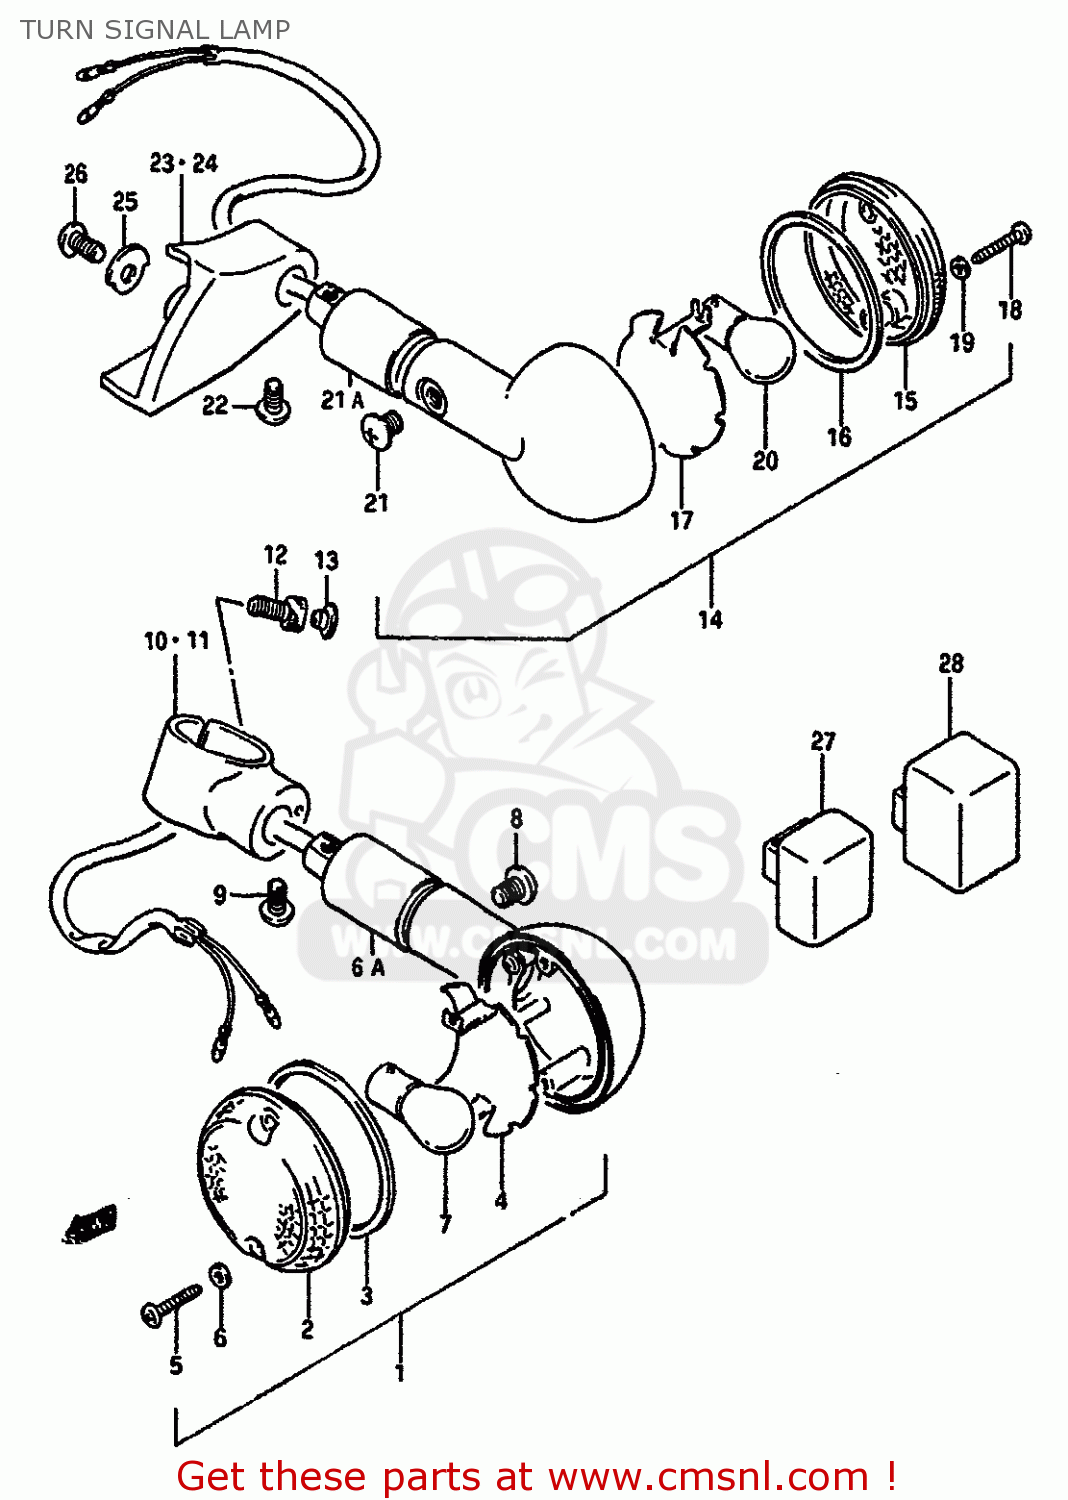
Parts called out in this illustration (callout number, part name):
1	LAMP ASSY,FR TURN SIGNAL
2	LENS
3	GASKET (NAS)
4	REFLECTOR
5	SCREW ,4X25
6	GASKET (NAS)
6A	STAY,TURNSIGNAL LAMP
7	BULB(12V21W)
8	SCREW
9	SCREW
10	BRACKET,FRONT TURN SIGNAL
11	BRACKET,FRONT TURN SIGNAL
12	BOLT
13	CAP(OD:10)
14	LAMP ASSEMBLY,REAR TURN SIGNAL
15	LENS
16	GASKET (NAS)
17	REFLECTOR
18	SCREW ,4X25
19	GASKET (NAS)
20	BULB(12V21W)
21	SCREW
21A	STAY,TURNSIGNAL LAMP
22	SCREW
23	BRACKET,RR TUR
24	BRACKET,RR TUR
25	WASHER,RR TURNSIGNAL BRACKET
26	SCREW 6X12
27	RELAY ASSEMBLY,TURN SIGNAL
28	RELAY ASSY,TUR
